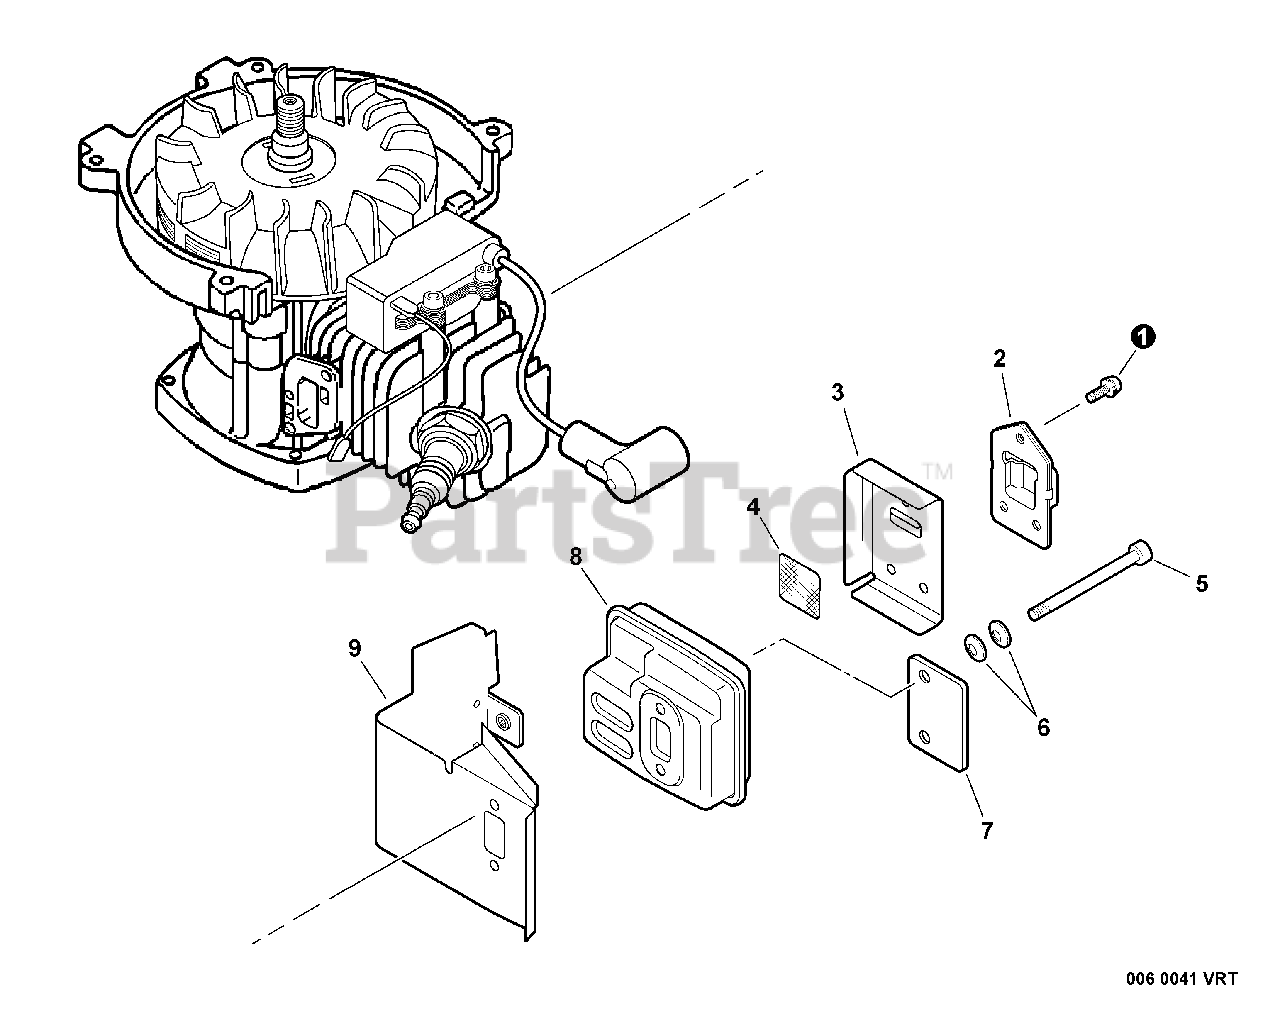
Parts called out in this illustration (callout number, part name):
1	SCREW - 4X12
2	GUIDE, EXHAUST
3	GASKET, EXHAUST
4	SCREEN, SPARK ARRESTOR
5	SCREW - 5X55
6	WASHER - CONICAL
8	MUFFLER
9	SHIELD, EXHAUST
